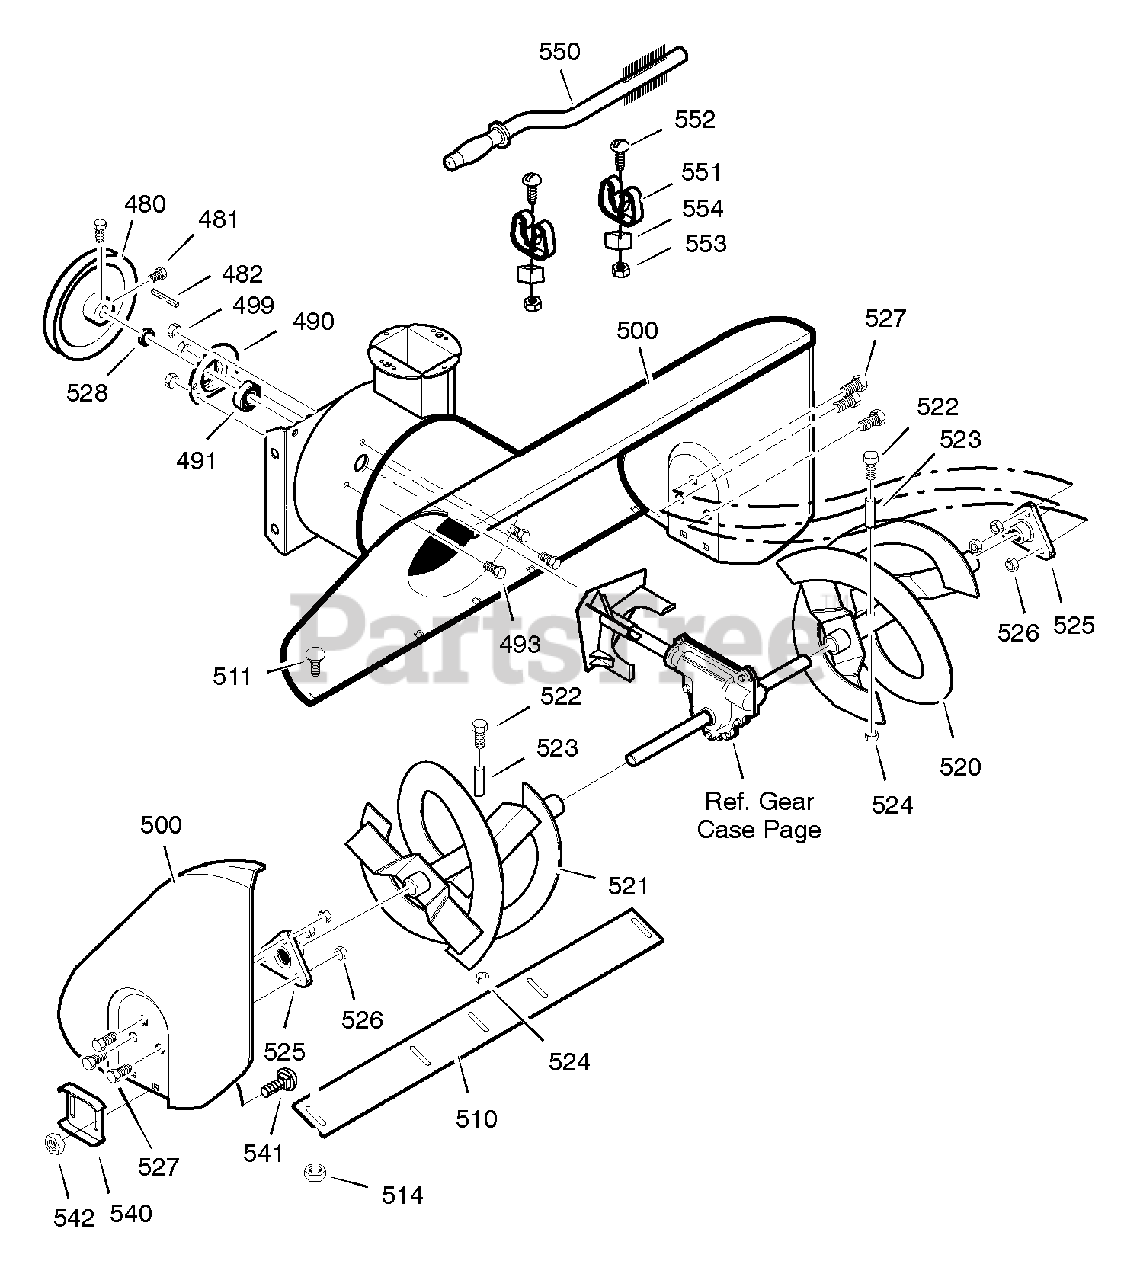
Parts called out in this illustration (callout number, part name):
480	PULLEY, V4L 8.4X .67
481	SCREW, 5/16-18 x 0.63
482	KEY, SQUARE 3/16 X
485	SPACER, FRICTION PULLEY
490	RETAINER, BALL
491	BEARING, BALL
493	BOLT, HEX 5/16-18 X
499	NUT, 5/16-18
500	HOUSING, ASSY
510	BLADE, SCRAPER
511	BOLT, 5/16-18 X 3/4
514	NUT, 5/16-18
520	AUGER, ASSY, LH
521	AUGER, ASSY, RH
522	SCREW
523	SPACER, SLEEVE
524	NUT, 1/4-20
525	BEARING, FLANGE
526	NUT, 5/16-18
527	SCREW, 5/16-18 x 3/4
540	SKID, HEIGHT ADJUST
541	BOLT, 5/16-18 X .75
542	NUT, 5/16-18
550	BRUSH, CLEANOUT
551	CLIP, RETAINER
552	SCREW
553	NUT
